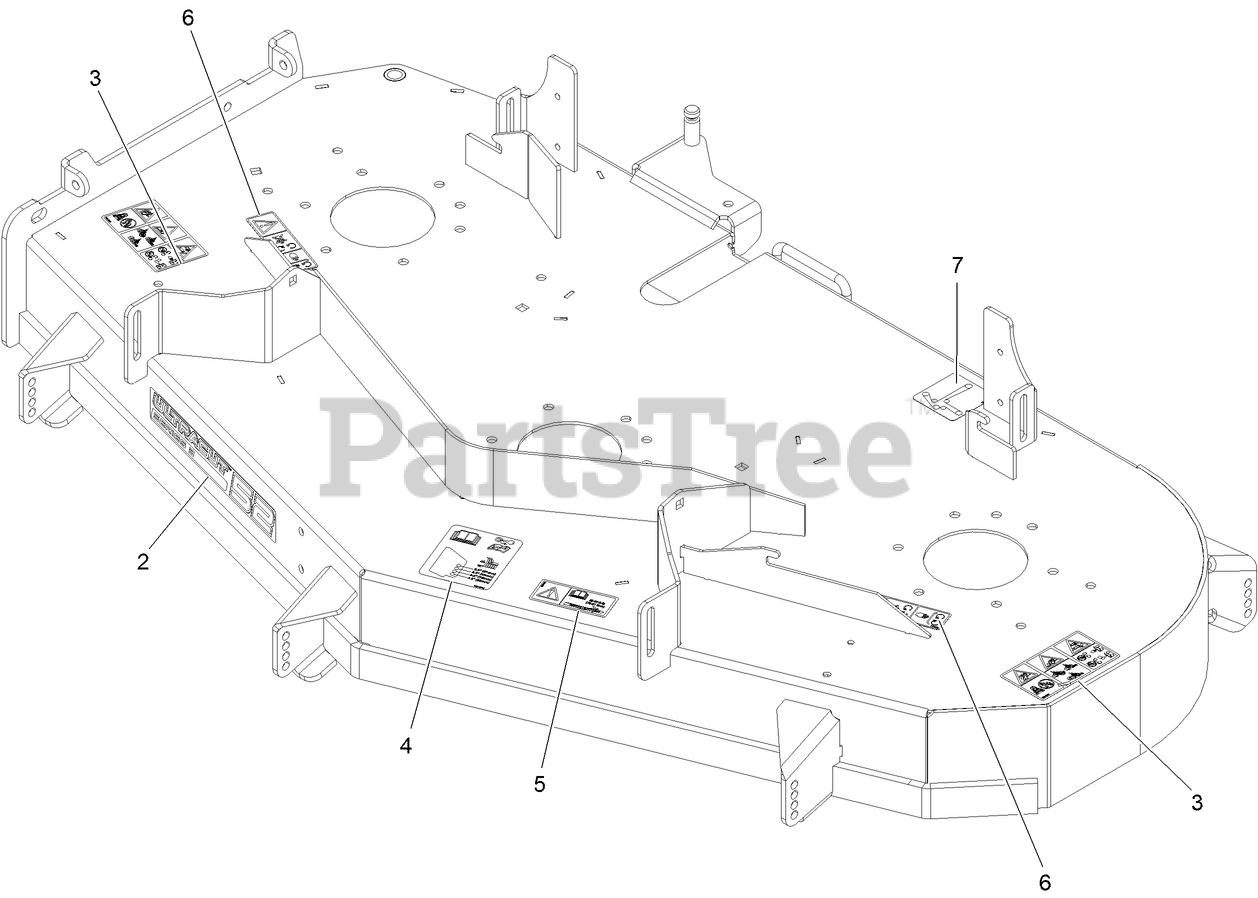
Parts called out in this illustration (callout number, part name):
2	DECAL-ULTRACUT 52 SERIES 3
3	DECAL-DANGER THROWN OBJECTS
4	DECAL-ROLLER, ANTI-SCALP
5	DECAL-TORQUE, BOLT
6	DECAL-COVER, MISSING
7	DECAL-ROUTING, BELT
